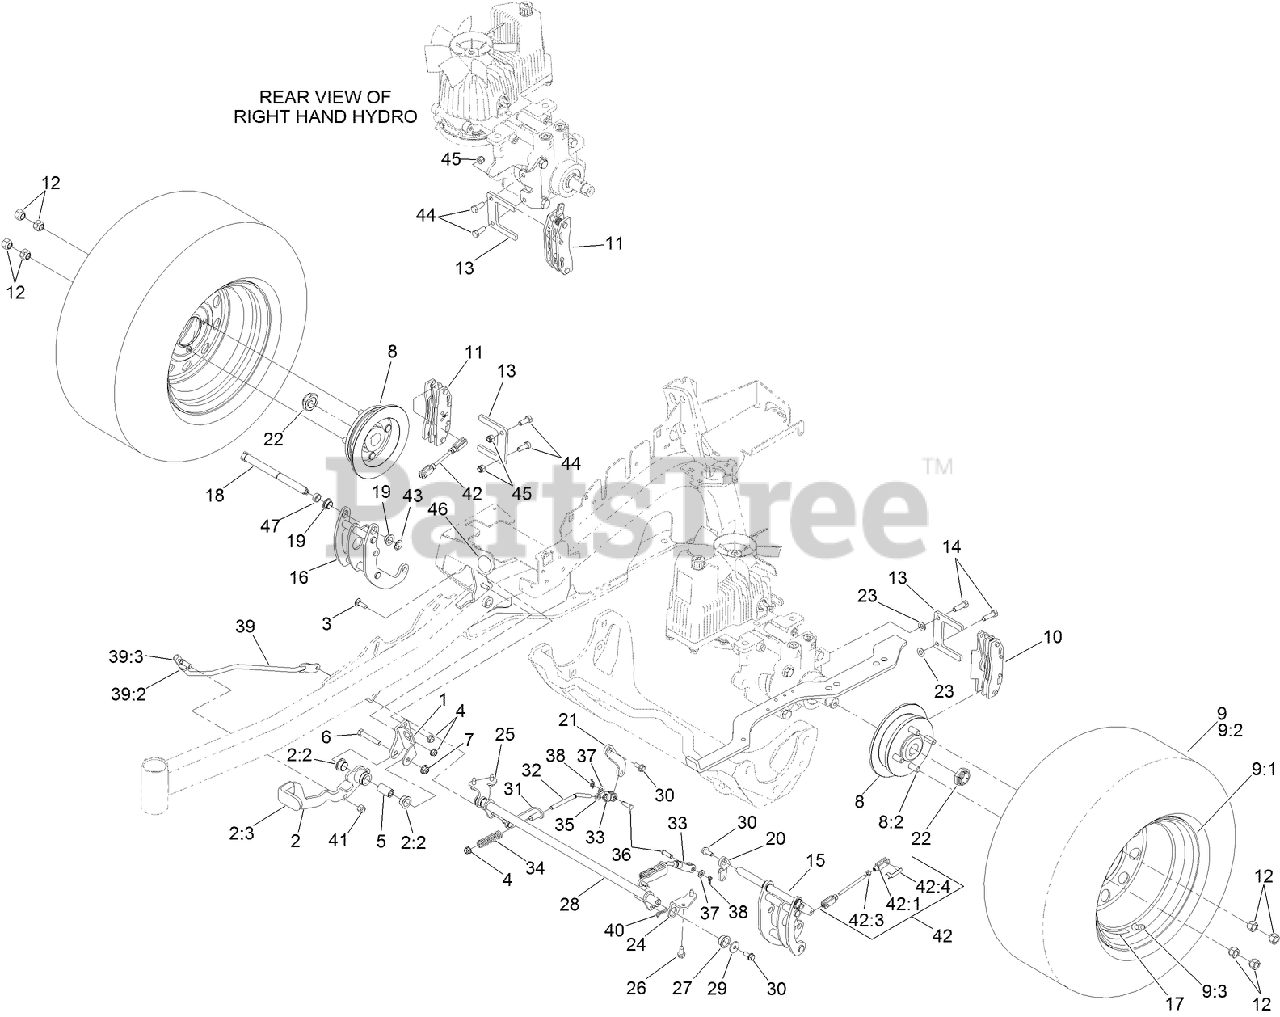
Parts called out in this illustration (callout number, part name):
1	BRACKET-MOUNT
2	BRAKE LEVER ASM W/ GRIP
2:2	BUSHING-FLANGE
2:3	GRIP-LEVER
3	BOLT-CARR
4	NUT-HF, NI
5	HANDLE-PIVOT, BRAKE
6	SCREW-HH
7	NUT-HF, NI
8	WHEEL HUB ASM
8:2	STUD-WHEEL
9	WHEEL AND TIRE ASM
9:3	STEM-VALVE
10	CALIPER-BRAKE
11	CALIPER-BRAKE, RH
12	NUT-LUG
13	PLATE-MOUNT, BRAKE
14	SCREW-LOCK, PATCH
15	MOUNT-BELLCRANK, LH
16	MOUNT-BELLCRANK, RH
17	DECAL-TORQUE, WHEEL HUB LUG
18	BELLCRANK
19	BUSHING
20	ARM-INNER, LH
21	ARM-INNER, RH
22	LOCKNUT
23	WASHER-FLAT
24	MOUNT-PIVOT, LH
25	MOUNT-PIVOT, RH
26	SCREW-HWHTF
27	BUSHING-FLANGE
28	SHAFT-CROSS
29	WASHER-FLAT
30	SCREW
31	BRACKET-L
32	LINKAGE-MID
33	YOKE-OFFSET
34	SPRING-COMPRESSION
35	NUT-JAM
36	PIN-CLEVIS
37	WASHER-PLAIN
38	PIN-COTTER, LOCKING
39	FRONT LINKAGE ASM
39:2	END-TIE ROD, RH
39:3	NUT-HJ
40	PIN-COTTER, LOCKING
41	NUT-LOCK
42	REAR LINKAGE ASM
42:1	YOKE
42:3	NUT-JAM
42:4	PIN-CLEVIS, SPRING
43	E-RING
44	SCREW-HH
45	NUT-LOCK, NI
46	DECAL-COVER
47	SPACER
